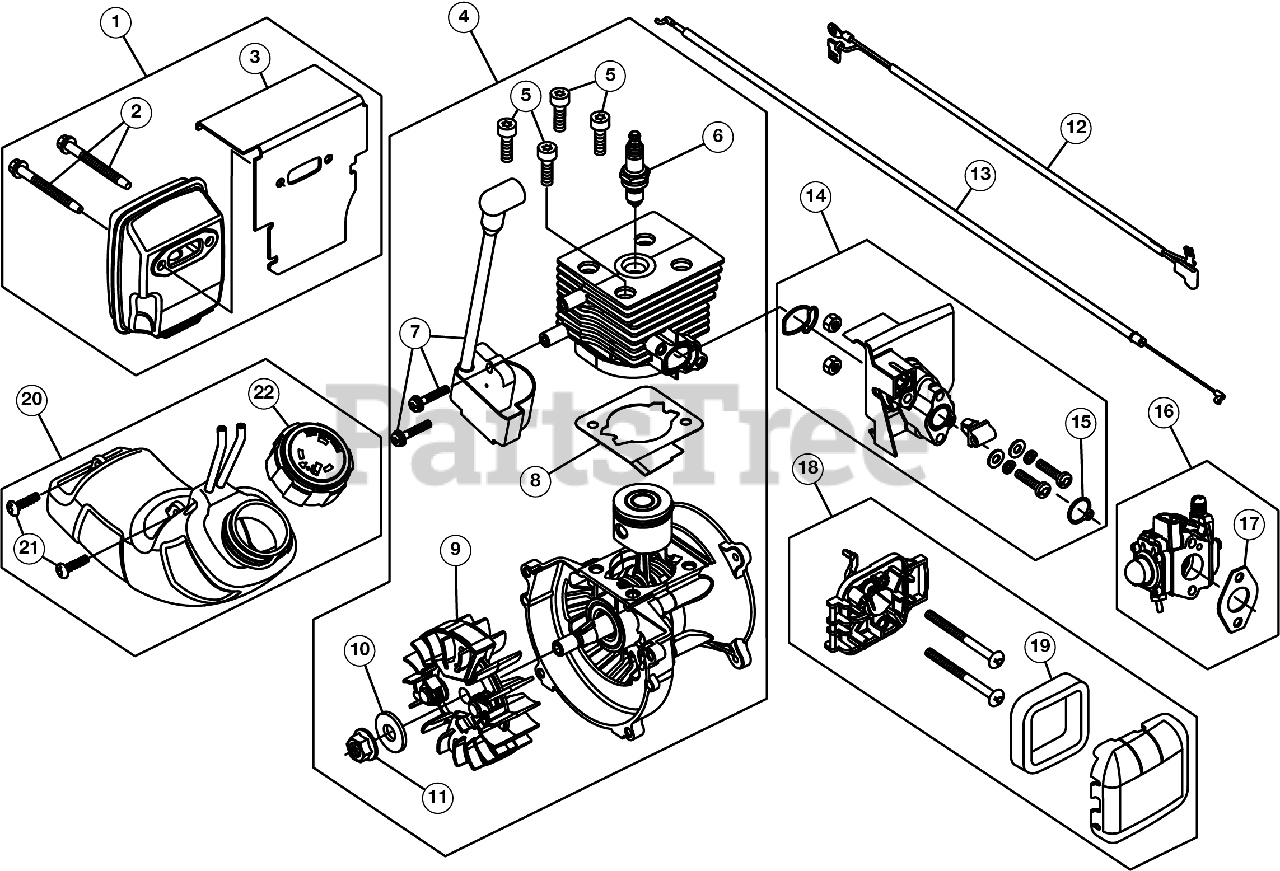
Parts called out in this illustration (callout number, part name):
1	MUFFLER ASSEMBLY 27CC
2	MUFFLER SCREW
3	MUFFLER GASKET
4	SHORT BLOCK
5	SCREW 1/4 x 20 x .8125
6	SPARK PLUG
7	MODULE ASSEMBLY
8	GASKET CYL
9	FLYWHEEL ASSEMBLY
10	WASHER .406X1.0X.095
11	NUT 3/8-24
12	LEAD WIRE
13	THROTTLE CABLE
14	INTAKE ASSEMBLY
15	O-RING
16	CARBURETOR ASSEMBLY
17	GASKET CARB
18	AIR CLEANER ASSEMBLY
19	AIR FILTER
20	FUEL TANK ASSEMBLY
21	SCREW 8-16 x 3/4
22	ASSEMBLY, FUEL CAP (RED TOP)
